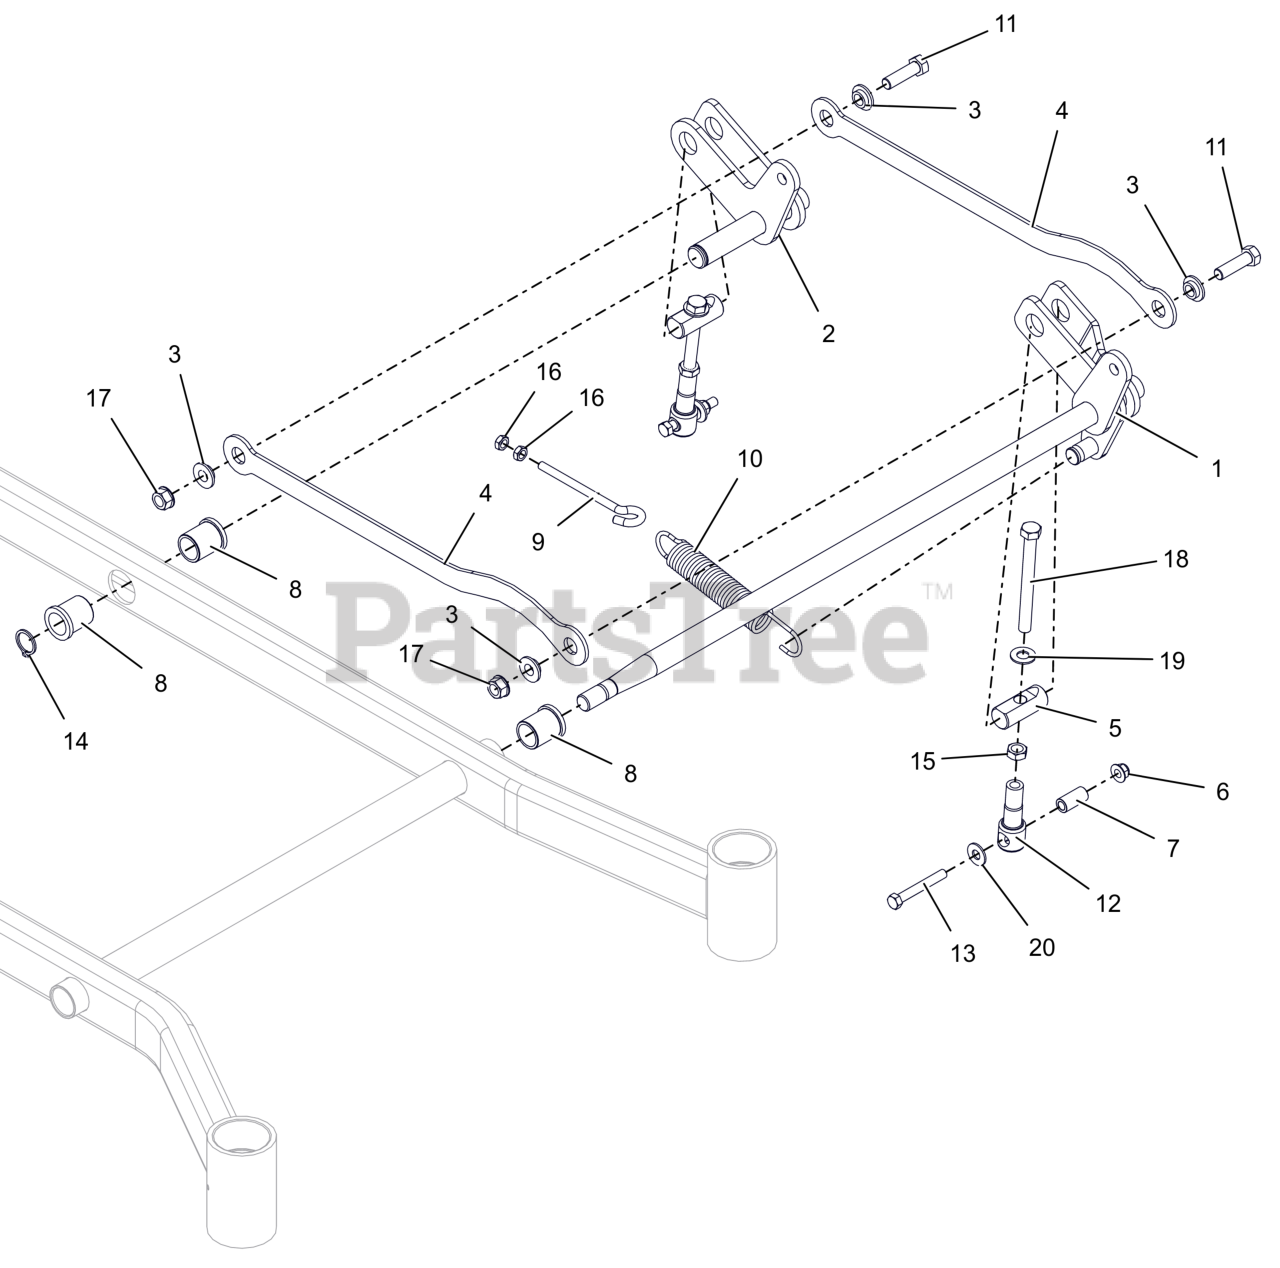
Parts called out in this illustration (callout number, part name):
1	FRT LH DECK LIFT ARM WMT- LF
2	REAR LH DECK LIFT ARM WMT- LF
3	BSHG-FLG .515X.750X.310X1.120
4	LINK, LIFT
5	PIN, DECK LIFT
6	NUT,NYL-FLG .38-16 GF ZCC
7	SPACER, DECK LEVELING
8	BSHG-FLG 1.00X1.25X1.50X1.50
9	BOLT,.38-16 X 4.25-.62 DIA EYE
10	SG-TENS .162X1.25X8.25 WLD 25
11	BLT, HEX .50-13X1.75 G5 ZCC
12	LINK, DECK LIFT FORMED
13	BLT, HEX .38-16X2.75 G8 ZCC
14	RG-RTNG-EXT 1.00X.078
15	NUT-JAM .500-13 G2 ZCC
16	NUT-JAM .375-16 G2 ZCC
17	NUT-LK-CTR-FLG .500-13 GG ZCC
18	BLT, HEX 0.5-13X5S GR5 ZCC
19	WSHR, FLT .557X1.040X.102 ZCC
20	WSHR,FLT .438X1.00X.083 ZCC
